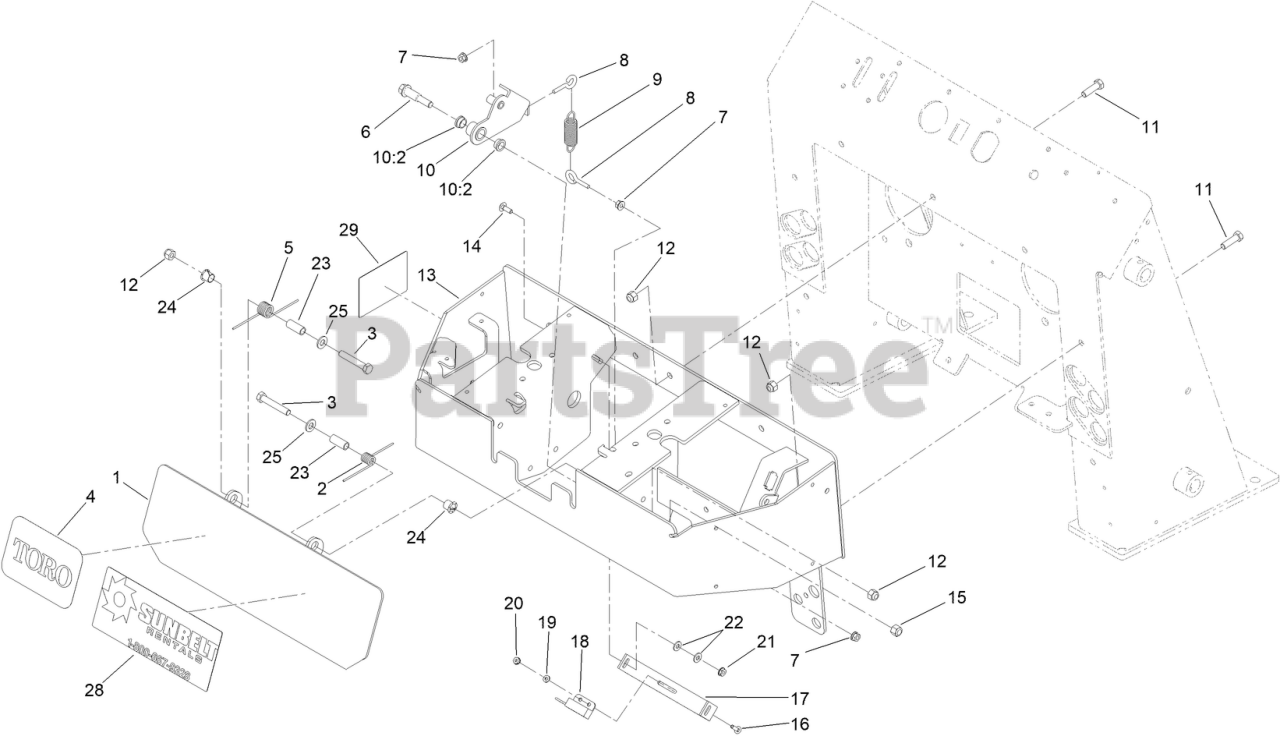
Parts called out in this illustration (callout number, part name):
1	PLATE-REVERSE
2	SPRING-TORSION, LH
3	SCREW-HH
5	SPRING-TORSION, RH
6	BOLT-SHOULDER
7	NUT-HHF
8	BOLT-EYE
9	SPRING-EXTENSION
10	NEUTRAL CENTERING LEVER ASM
10:2	BUSHING-FLANGE
11	SCREW-HH
12	NUT-LOCK, NI
13	PANEL-CONTROL
14	BOLT-CARR
15	NUT-LOCK
16	SCREW-CARR
17	PLATE-SWITCH
18	SWITCH-PROXIMITY
19	WASHER-FLAT
20	NUT-KEPS
21	NUT-KEPS
22	WASHER-FLAT
23	SPACER-SPRING
24	BUSHING-NYLINER
25	WASHER-FLAT
28	DECAL-S8HSW4X10
29	DECAL-SRVSW3X4
